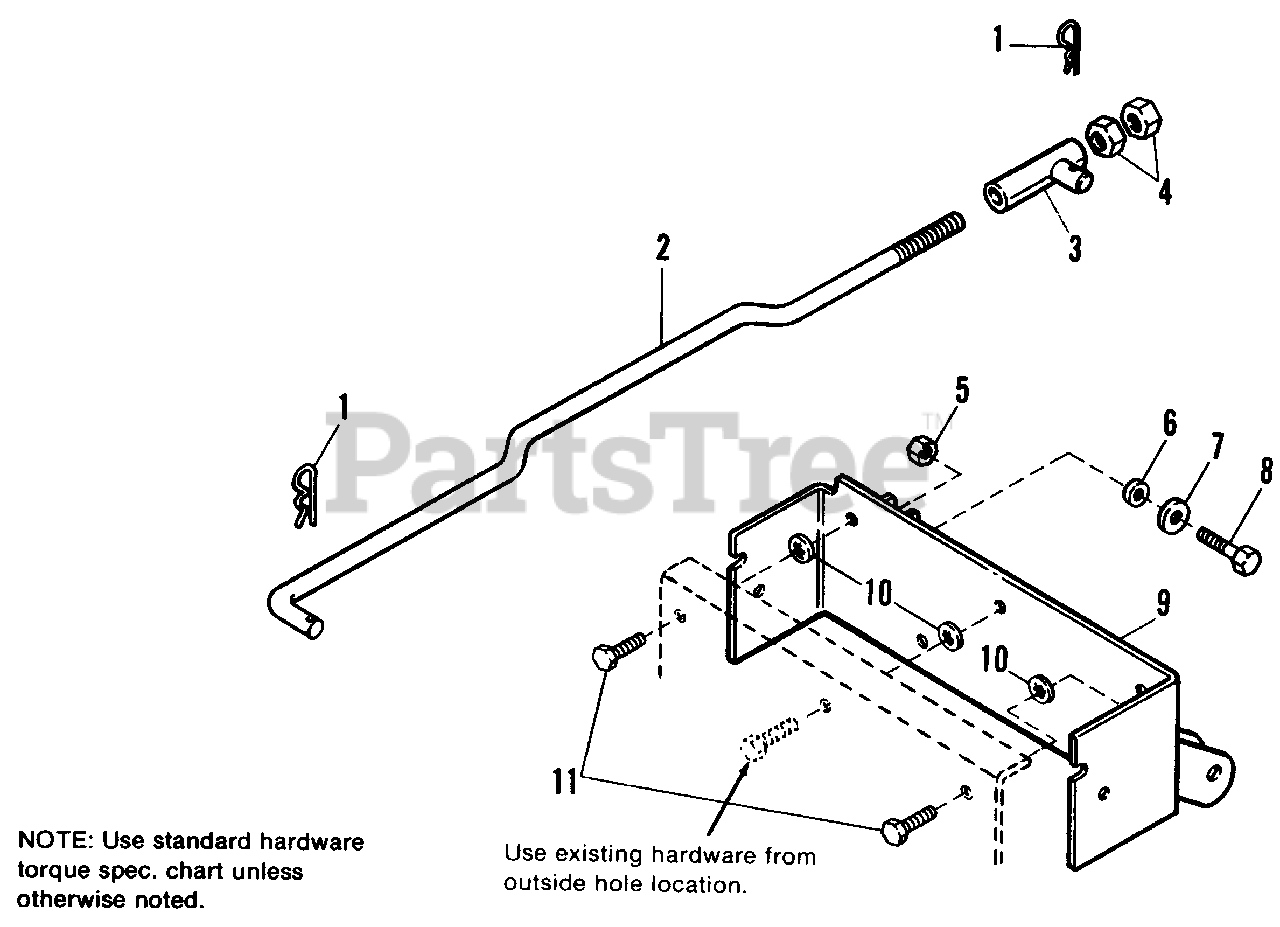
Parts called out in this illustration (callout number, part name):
1	HAIR PIN CLIP
3	ROD GUIDE ASSY.
4	NUT, Hex, Jam, 1/2-20
5	NUT, Hex, 5/16-18 x 1
7	WASHER, Flat, 5/16
8	BOLT, Hex, 5/16-18 x 7/8
9	HITCH ASSY.
11	CAPSCREW, 3/8-16 x 1-1/4 (Used on early models only. Use existing hardware for later models.)
